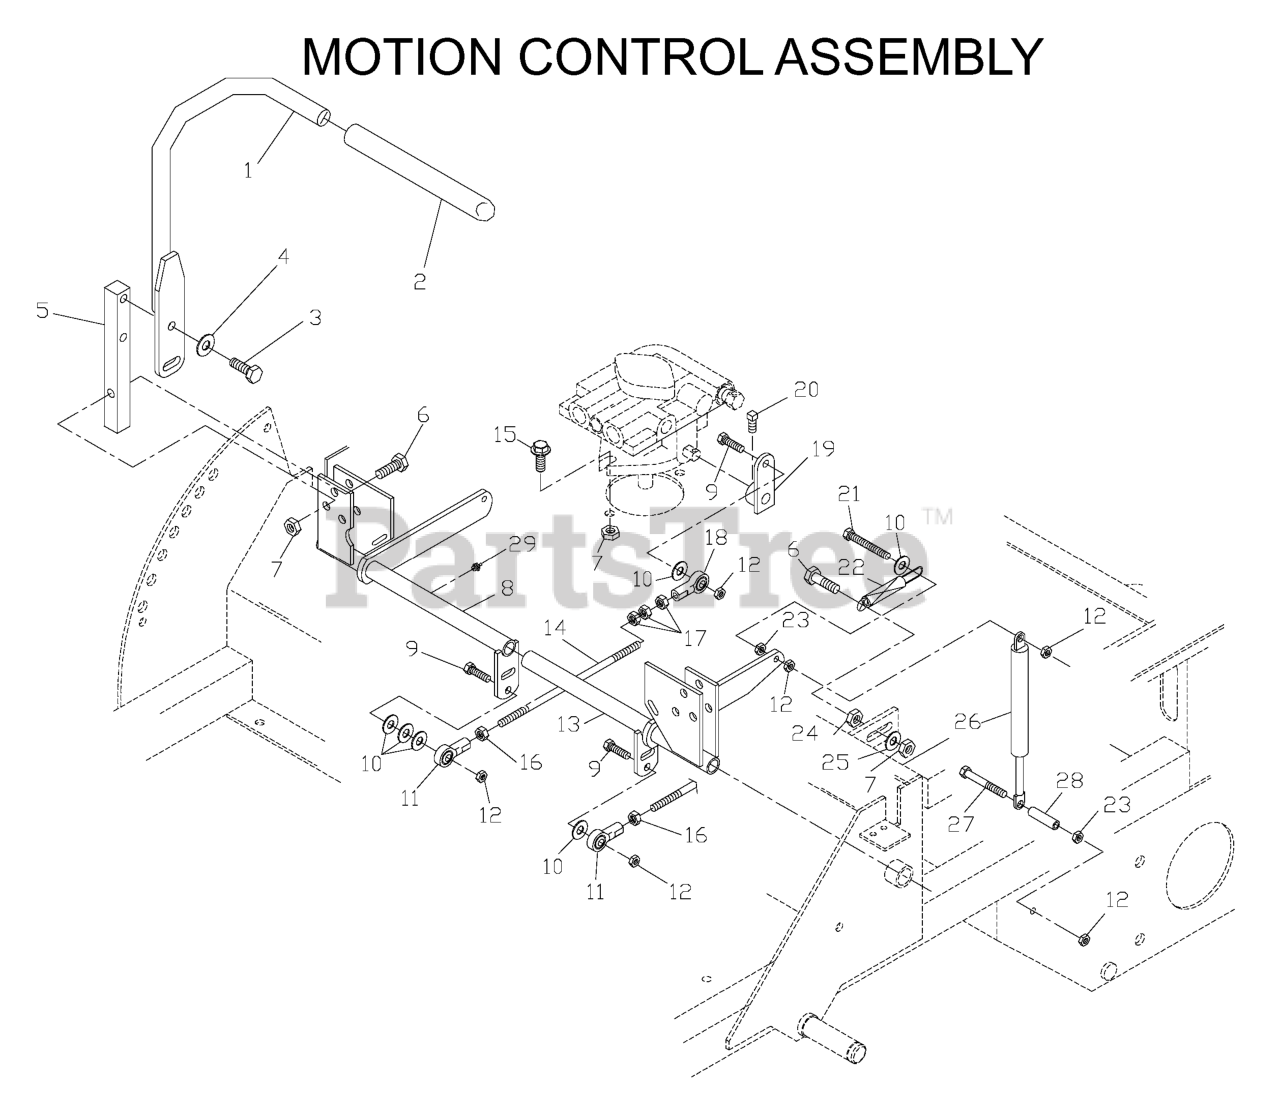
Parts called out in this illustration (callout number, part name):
1	CONTROL LEVER WELDMENT
3	HCS 3/8-16X1.GRD.5.ZD
4	WASHER, 3/8 DISC SPRING SPEC
5	CONTROL ARM
6	HCS 3/8C X 1 1/2
7	NUT 3/8C CENTERBLOCK
8	CONTROL WELDMENT, RIGHT
9	HCS 5/16C X 1 1/4
10	WASHER 5/16 FLAT
11	BALL JOINT, LEFT HANDED
12	NUT 5/16C CENTERLOCK
13	CONTROL WELDMENT, LEFT
14	PUMP CONTROL LINK
15	4CS 3/8C X 1 SERRATED HEAD
16	NUT 5/16F LEFTHAND
18	BALL JOINT, RIGHT HANDED
19	CONTROL ARM, PUMP
20	SCREW 5/16C X 5/8 SQ HEAD
21	TAP BOLT 5/16C X 2 1/4
23	NUT 5/16C WHIZ
24	NUT 3/8C WHIZ
25	WASHER 3/8 FLAT
27	HCS 5/16C X 2 3/4 GRADE 8
29	ZERK
